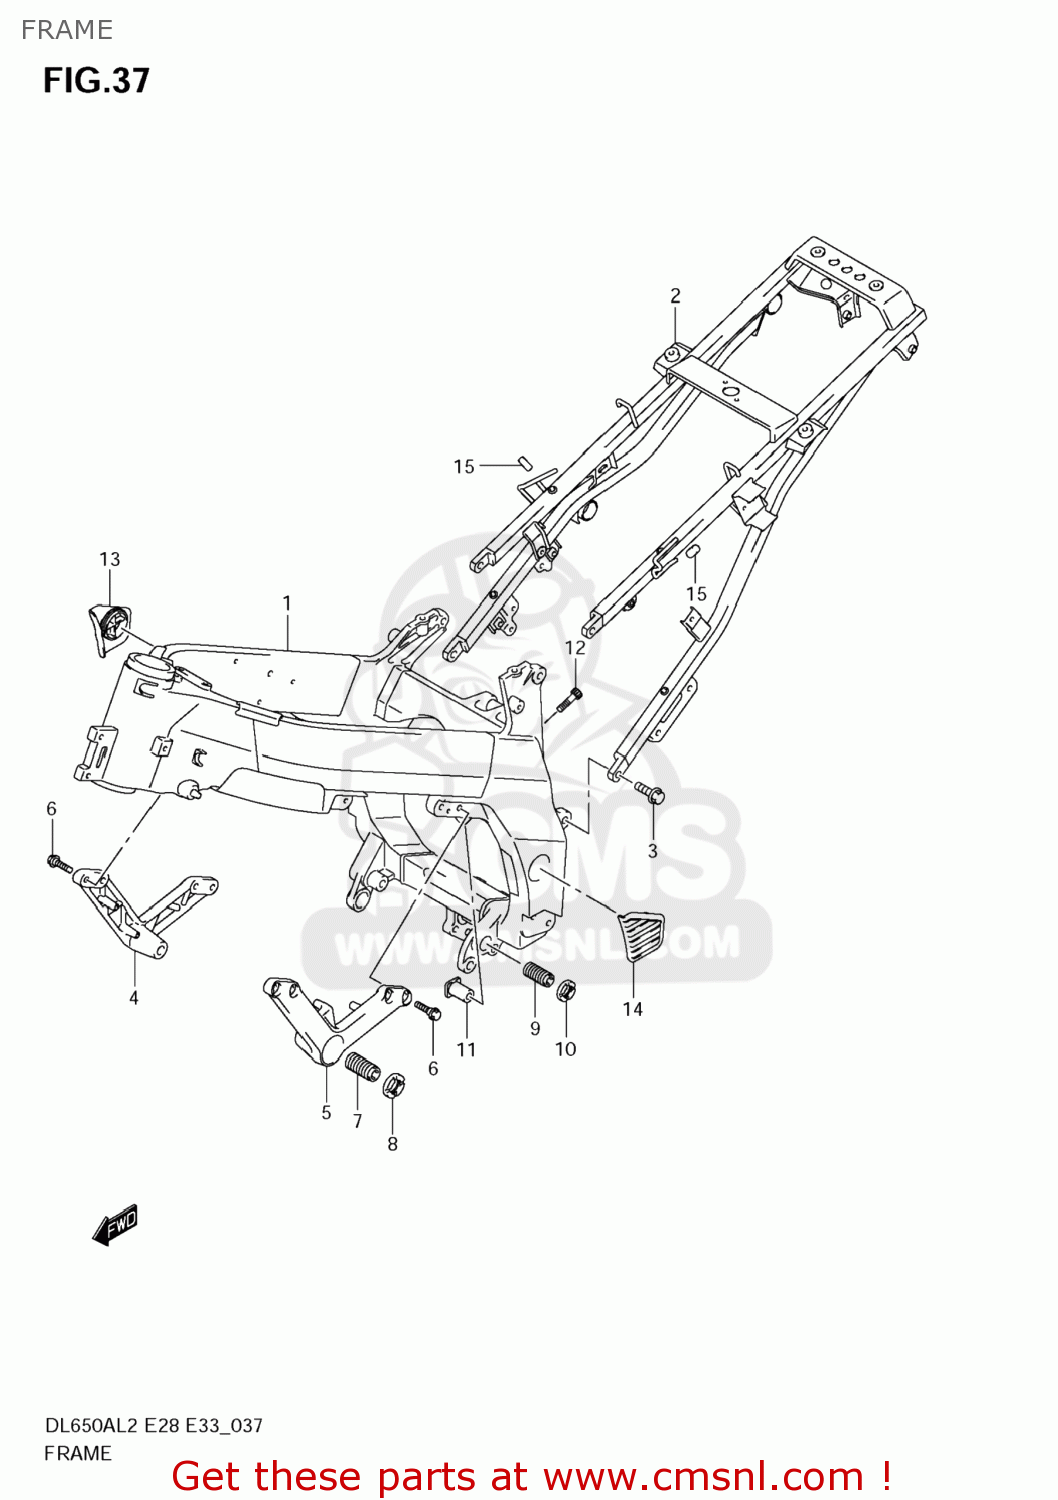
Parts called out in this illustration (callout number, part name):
1	FRAME
2	RAIL,SEAT
3	BOLT(10X30)
4	BRACKET,ENGINE MOUNTING,R
5	BRACKET,ENGINE MOUNTING,L
6	BOLT(8X30)
7	BOLT,CRANK CASE ADJUST CTR
8	NUT,CRANK CASE ADJUST CTR
9	BOLT,CASE LWR & RR HEAD ADJ
10	NUT,CRANK CASE ADJUST LWR
11	SPACER,MOUNTING RR UPR,R
12	BOLT(8X38)
13	COVER,PIVOT,R
14	COVER,PIVOT,L
15	CAP
